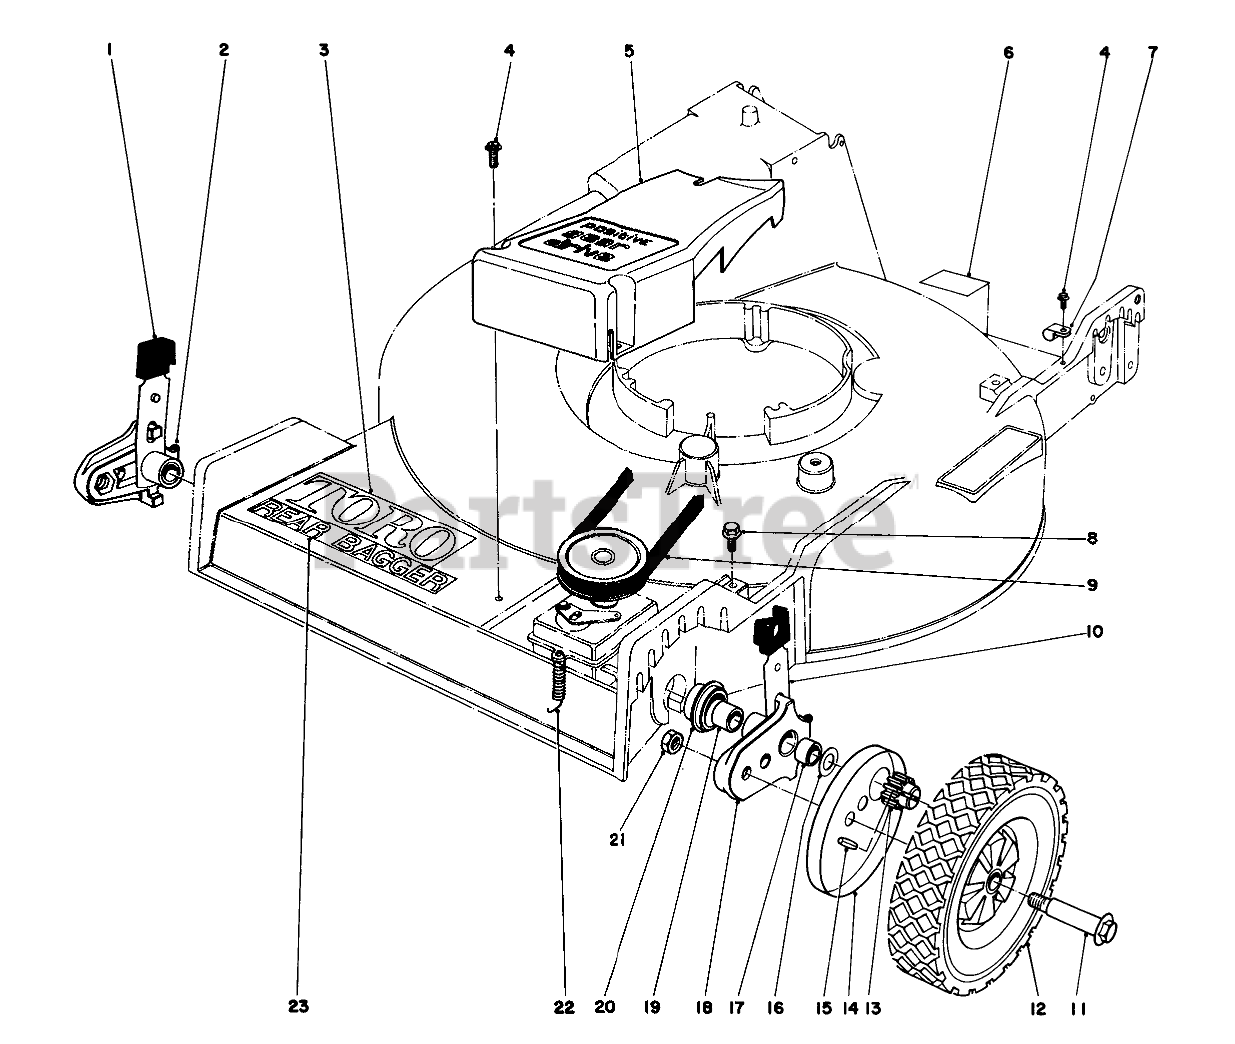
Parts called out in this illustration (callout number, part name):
1	KNOB-ARM
2	FITTING-GREASE
3	TORO LOGO DECAL
4	SCREW
5	BELT COVER
6	Greasing Sticker
7	CLAMP-NYLON
8	SCREW-HWHTF
9	V BELT
10	Spring Arm
11	BOLT-WHEEL
12	Wheel & Tire Assembly
13	Pinion Gear
14	Cover-Wheel
15	Pin
16	WASHER-THRUST
17	Bushing
18	Pivot Arm Assembly (Incl. Ref. #2, 17 & 19)
19	Bushing
20	END CAP
21	Nut
22	TENSION SPRING
23	DECK DECAL
